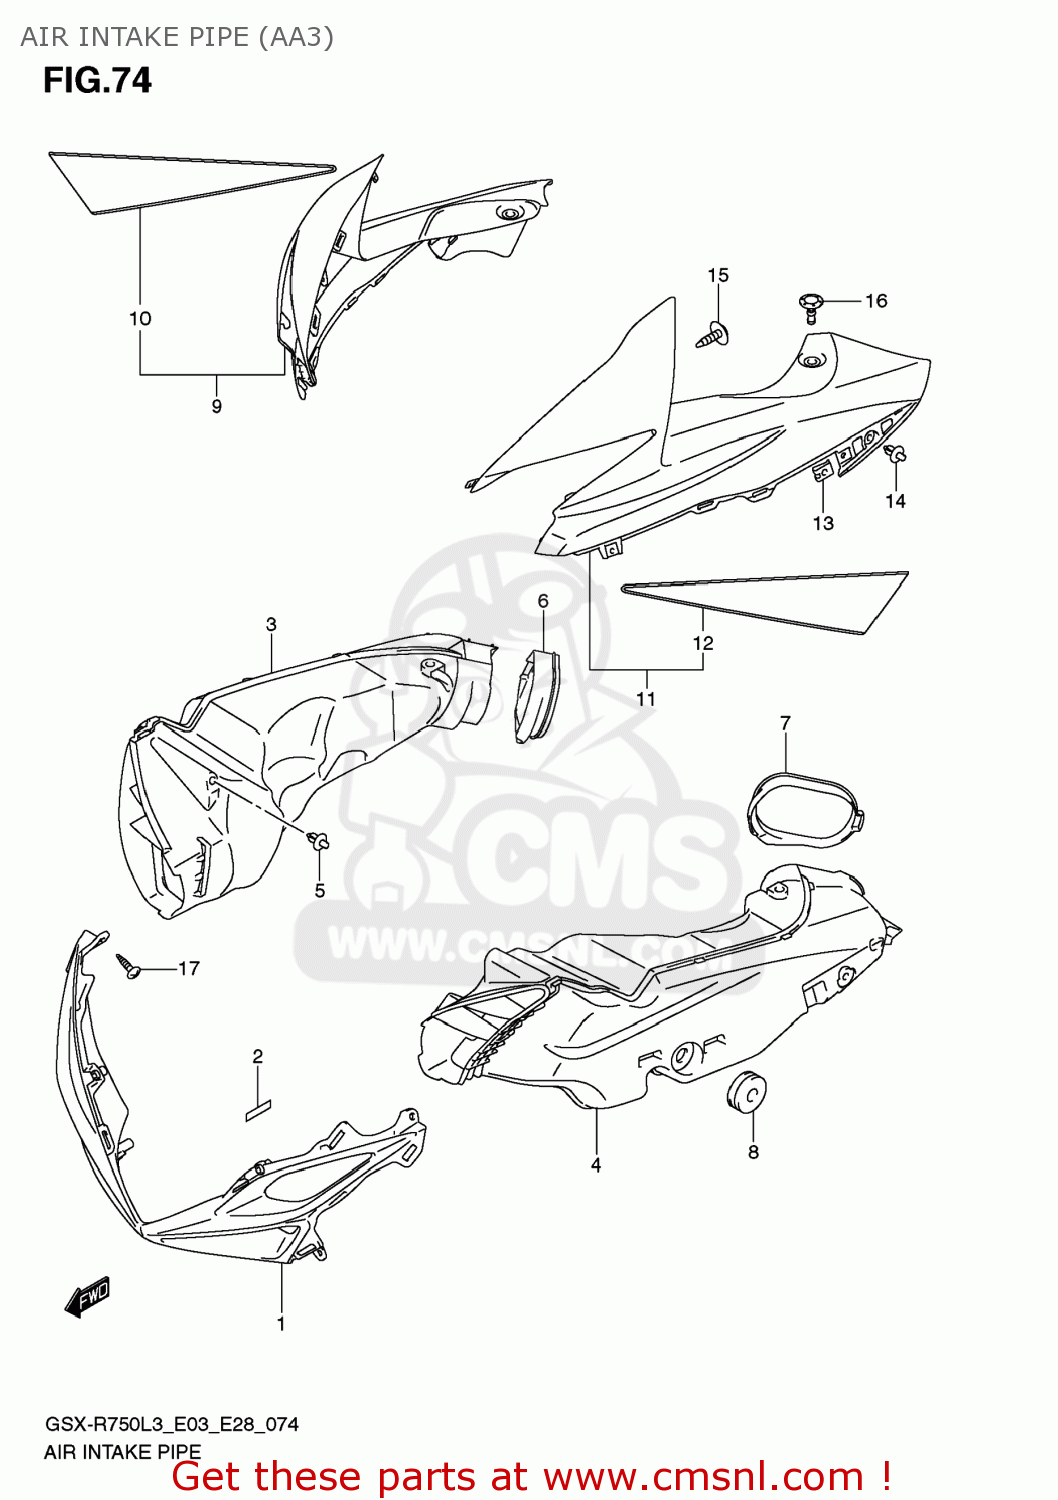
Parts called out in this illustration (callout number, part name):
1	COVER,INTAKE
2	TAPE(6X25X0.13)
3	PIPE,AIR INTAKE,R
4	PIPE,AIR INTAKE,L
5	CLIP(BLACK)
6	MOLDING,AIR INTAKE,R
7	MOLDING,AIR INTAKE,L
8	CUSHION
9	COVER,INTAKE,R(BLACK)
10	TAPE,INTAKE COVER,R
11	COVER,INTAKE,L(BLACK)
12	TAPE,INTAKE COVER,L
13	NUT
14	CLIP(BLACK)
15	SCREW(5X12)
16	CLIP
17	SCREW
